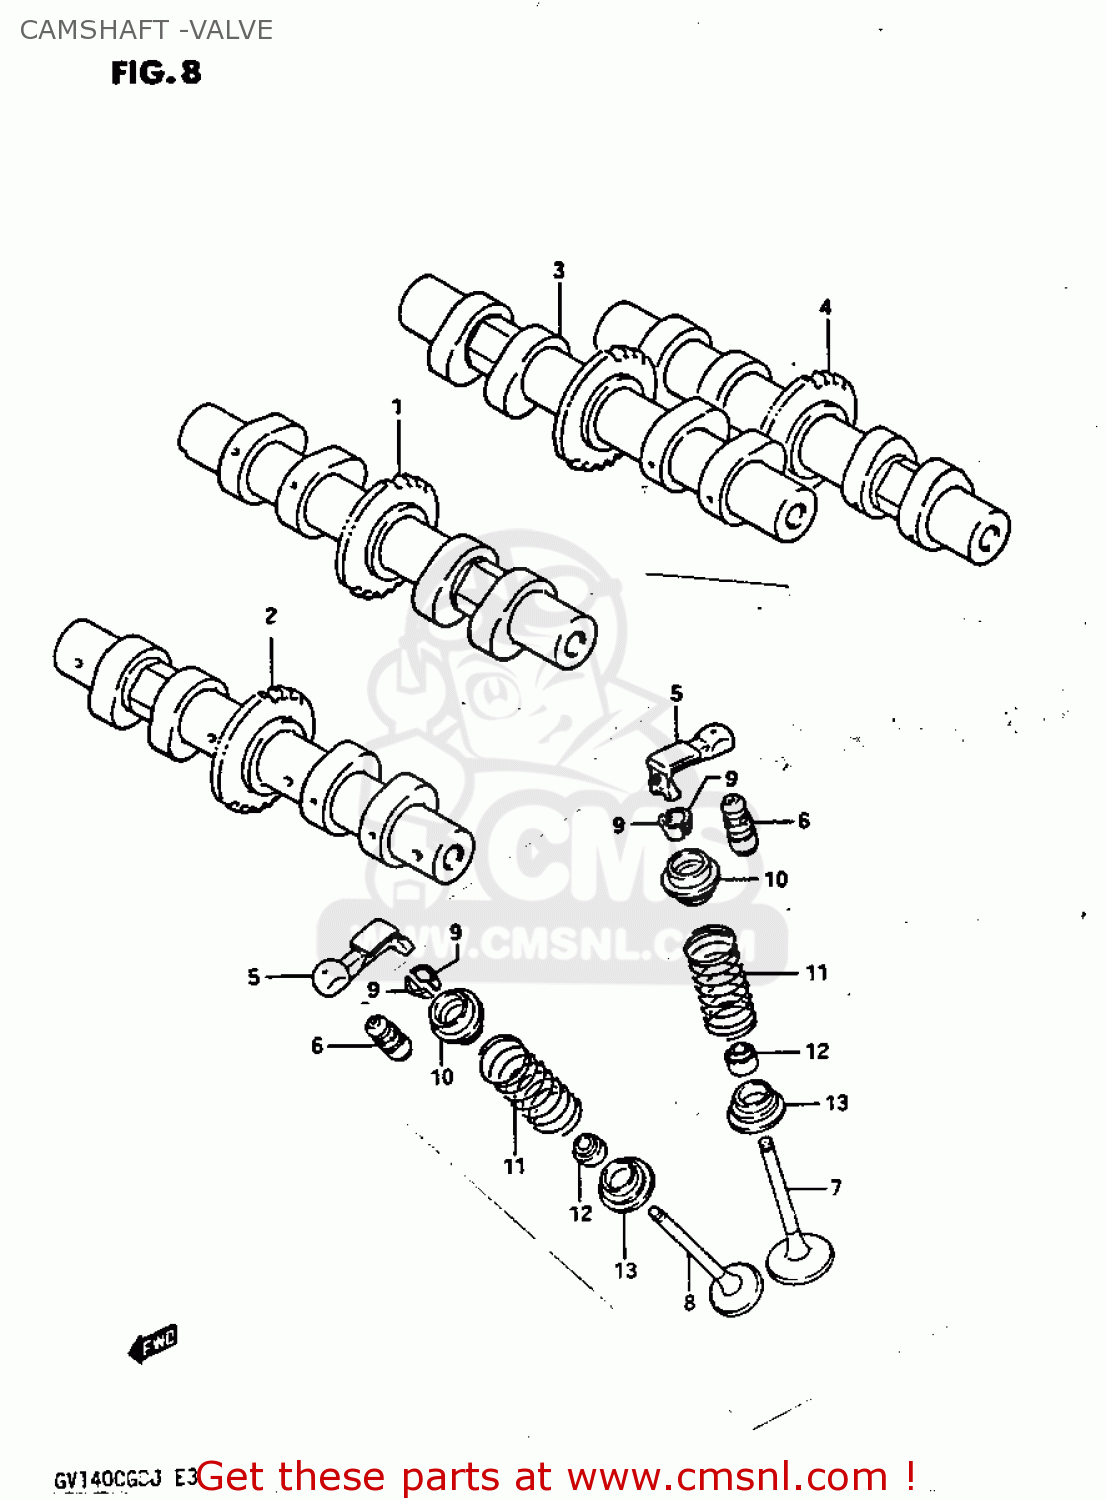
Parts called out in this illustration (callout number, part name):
1	SHAFT COMP,INTAKE FRONT CAM
2	SHAFT,EXHAUST FRONT CAM
3	SHAFT COMP,INTAKE REAR CAM
4	SHAFT,EXHAUST REAR CAM
5	ARM,VALVE ROCKER
6	ADJUSTER,HYDRAULIC VALVE
7	VALVE,INTAKE
8	VALVE,EXHAUST
9	COTTER VALVE
10	RETAINER,VALVE SPRING
11	SPRING,VALVE
12	SEAL,OIL(5X10.5X8.4)
13	SEAT,VALVE SPRING
